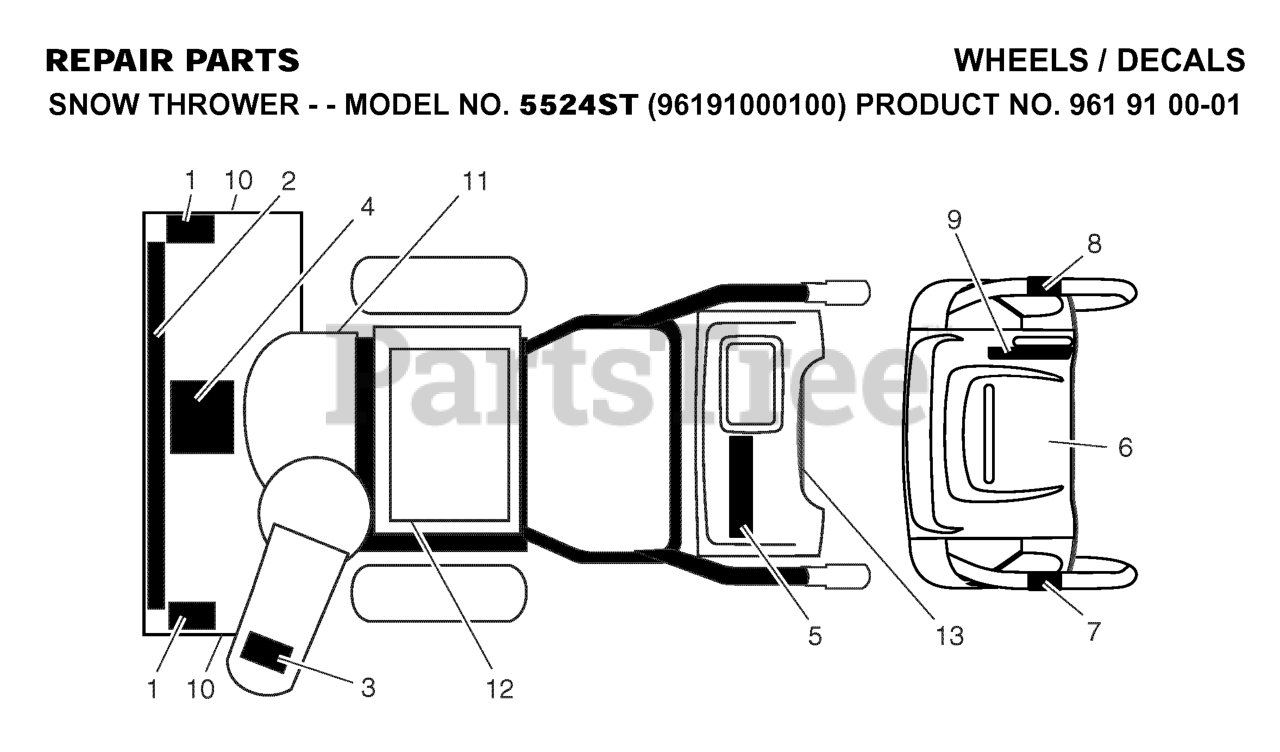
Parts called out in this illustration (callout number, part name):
4	DECAL.AUGER."
6	DECAL.CONSOLE.INSTRUCTION
11	DECAL.BELT.GUARD.
13	DECAL.FENDER
